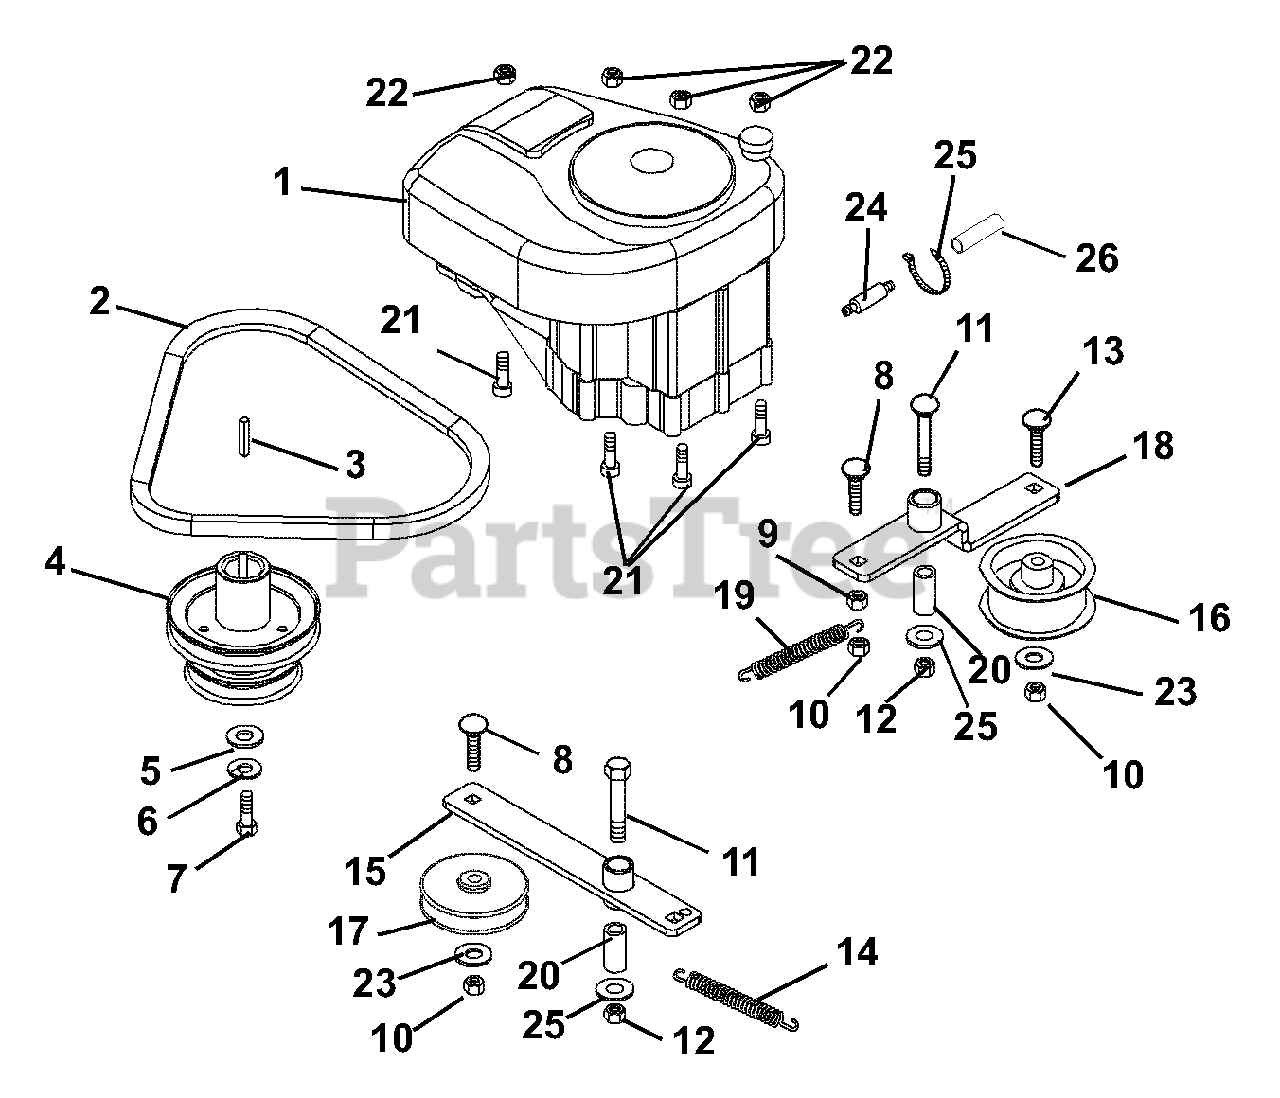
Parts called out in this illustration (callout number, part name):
1	Group, Engine 12HP Intek (062)
1	Group, Engine 10HP Intek (060)
2	V-Belt 4L-Section 30.219 x .547
3	Key, Straight .25 x 1.75 x .25
4	Stack, Sheave (060, 062)
5	Washer, Flat Steel
6	Washer, Locking .44 x .109 Regular
7	Bolt, Hex .44-20 x 1.75 Grade 5
8	Bolt-Round Head Square Neck .38-16 x 1.25 Grade 5
9	Nut-Flange .375-16
10	Nut, Locking Top Flange .38-16
11	Bolt, Hex .50-13 x 2.25 Grade 5
12	Nut, Locking Nylock Thin .50-13
13	Bolt-Round Head Square Neck .38-16 x 2.00 Grade 5
14	Spring, Tension .095 x .50 x 5.50
15	Idler, Drive
16	Sheave 3.25 x 1.25
17	Idler, V 3 x .38
18	Idler, 32" Deck PTO
19	Spring, Extension.093 x .75 x 4.00
20	Bushing-Sleeve .50 x .75 x 1.56
21	Screw, Socket Head Button Head .31-18 x 1.50 Grade 8
22	Nut-Locking-Top-Flange .31-18
23	Washer-Flat-Steel .38 x .875 x .083
24	Valve, Oil Drain
25	Cable Tie
26	Tube, Oil Drain
27	Washer-Flat-Steel .563 x 1.38 x .109
